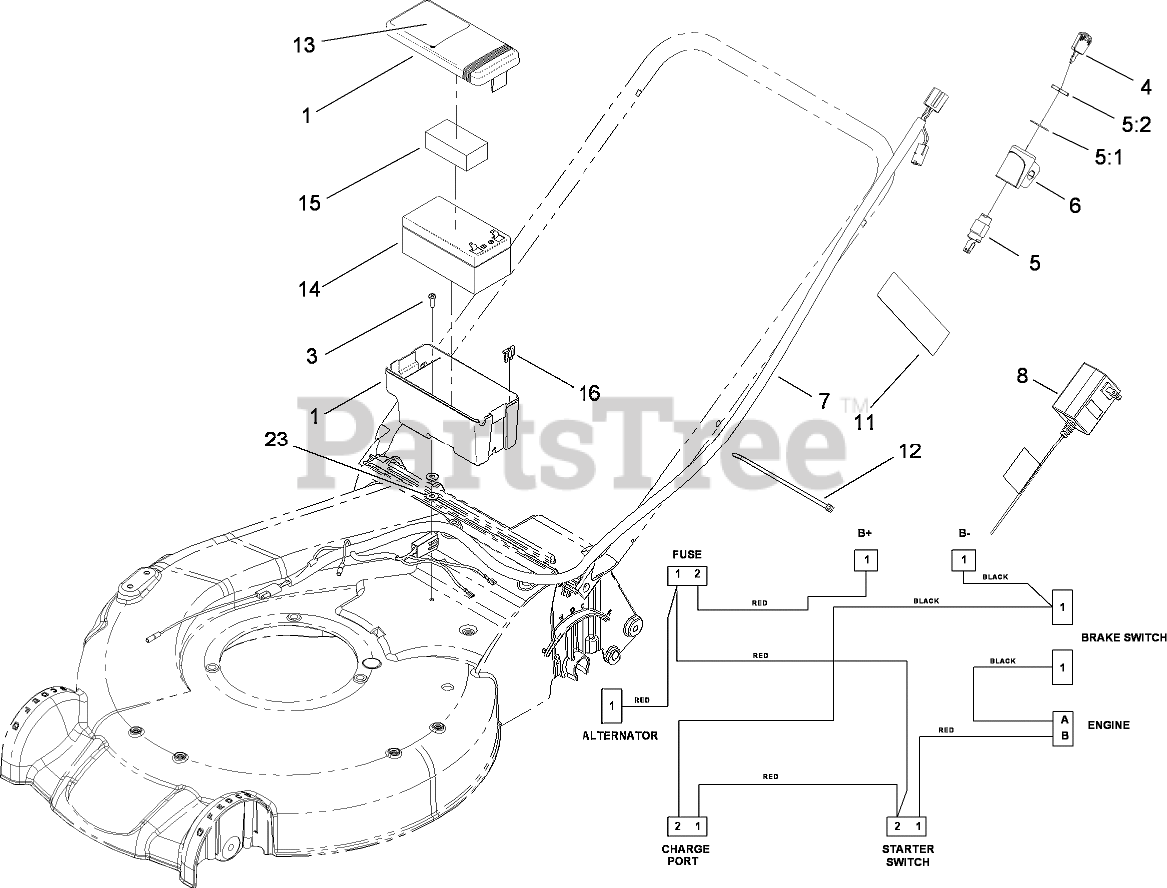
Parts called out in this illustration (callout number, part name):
1	BATTERY BOX ASM
5	STARTER SWITCH ASM
5:1	WASHER-TOOTH, INTERNAL
5:2	NUT-HH
6	MOUNT-SWITCH
7	HARNESS-WIRE
8	CHARGER-12 VOLT
11	DECAL-WARNING
12	TIE-CABLE
13	DECAL-INSTRUCTIONAL
14	BATTERY-WET
15	FOAM-BATTERY, TOP
16	FUSE-40 AMP
23	WASHER-FLAT
